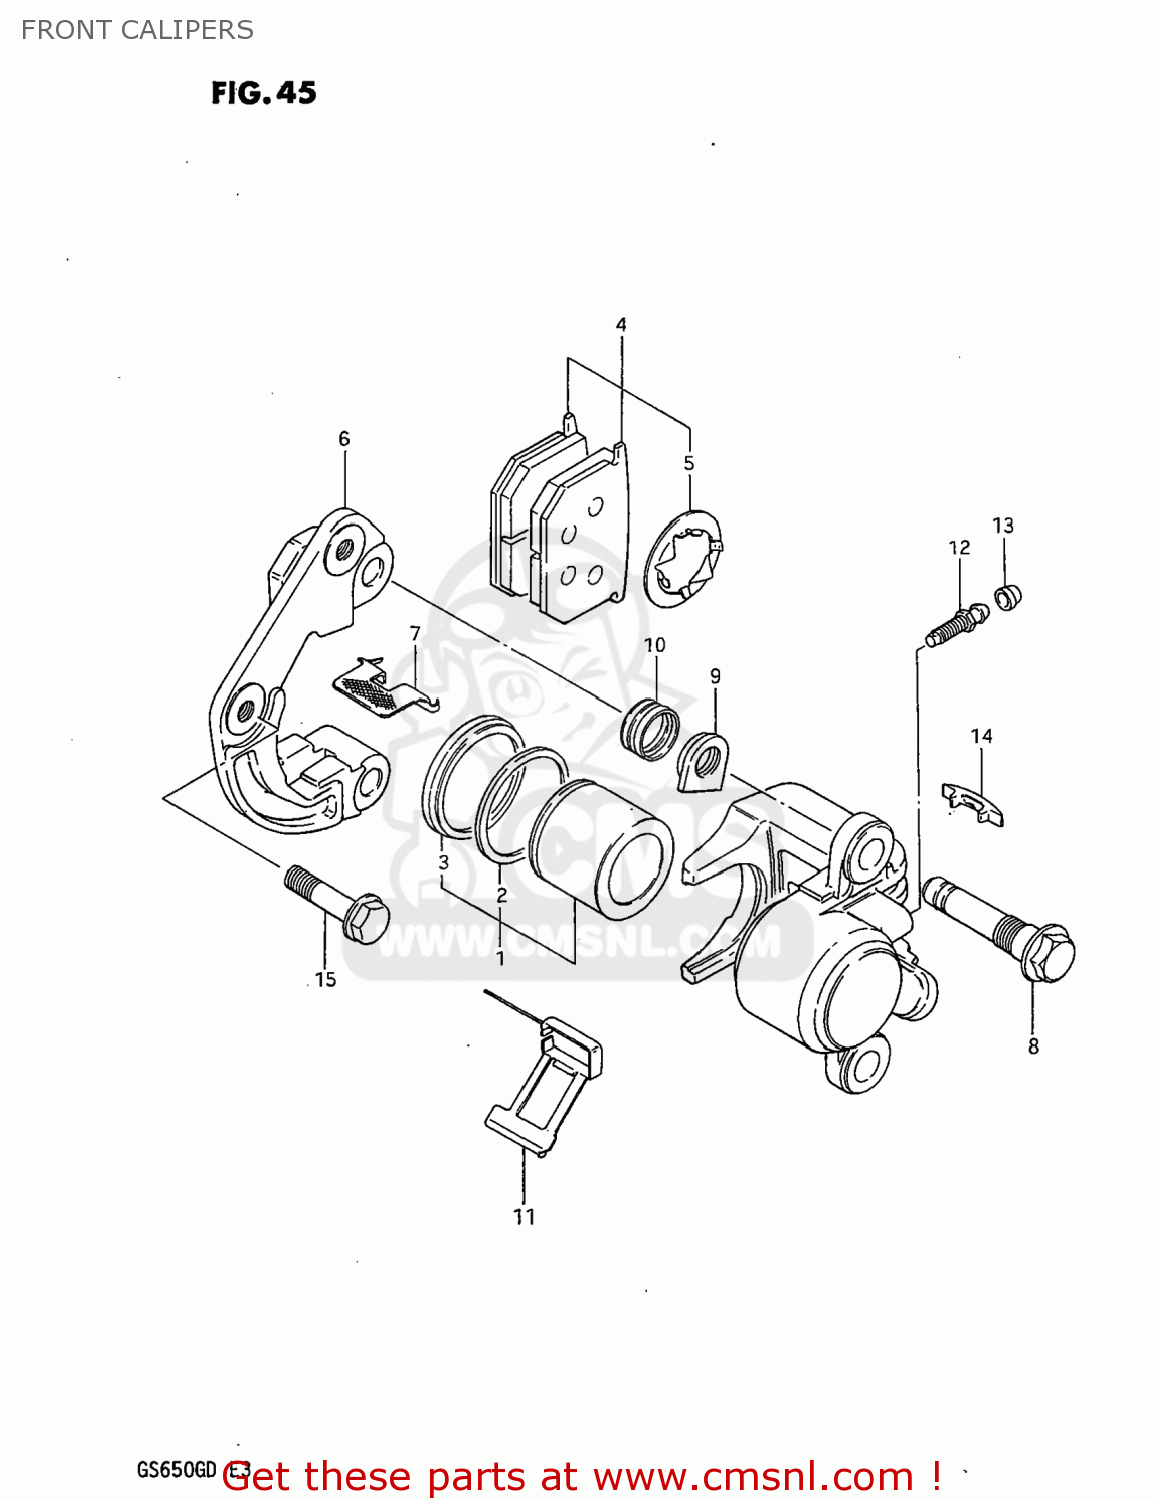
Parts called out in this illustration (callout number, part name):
1	PISTON SET
2	SEAL,PISTON
3	BOOT,PISTON
4	PAD & SHIM SET (MCA)
5	SHIM,PAD
6	HOLDER,CALIPER,LEFT
7	PAD,GUIDE
8	AXLE,CALIPER
9	NUT,CALIPER AXLE
10	BOOT
11	SPRING
12	BREATHER
13	CAP,BLEEDER PL
14	COVER,INDICATOR
15	BOLT(10X37)
